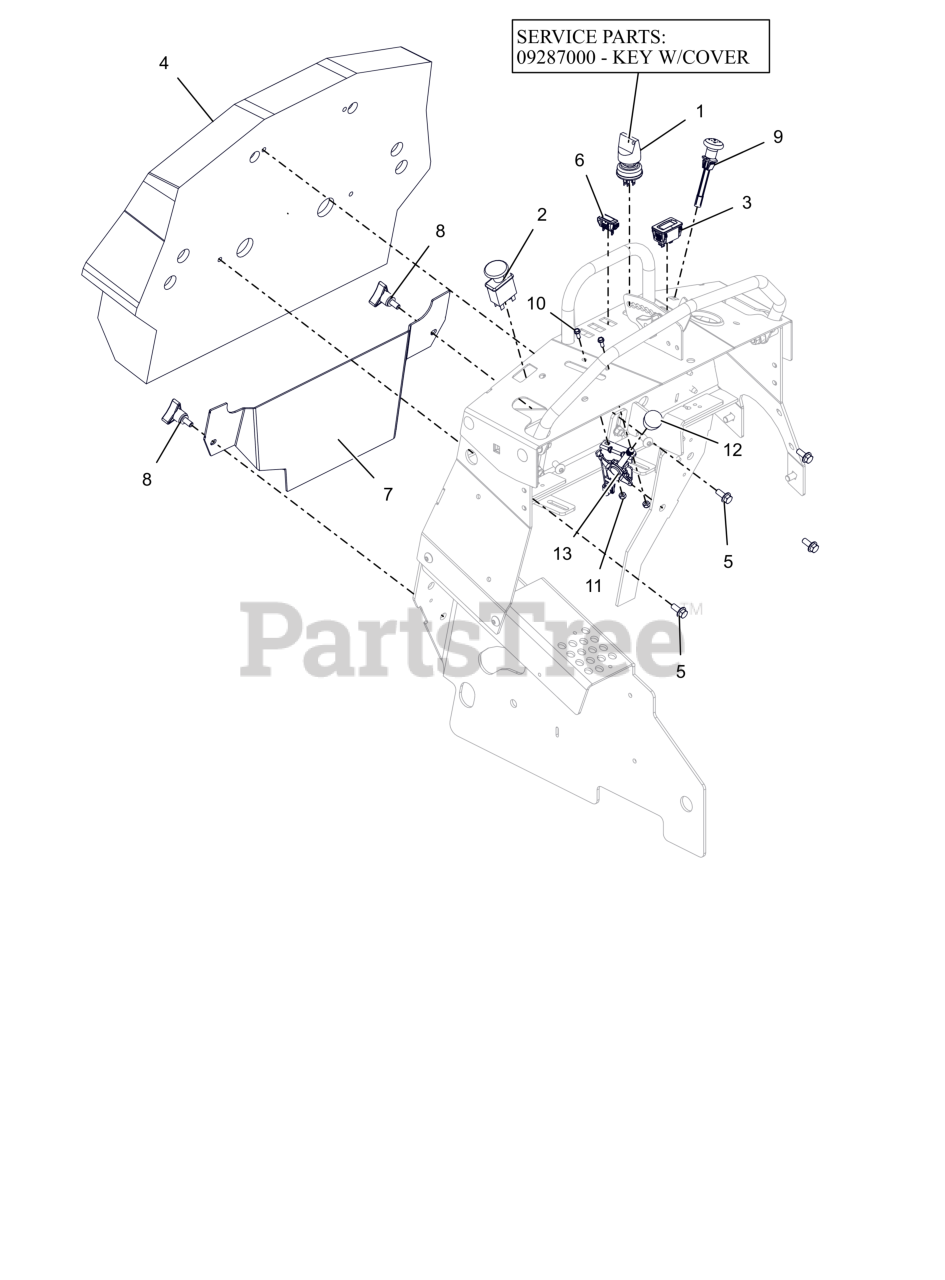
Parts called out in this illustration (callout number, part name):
1	SWITCH, IGNITION
1	KEY, W/ SHIELD
2	SWITCH, CLUTCH
3	HOUR METER
4	PAD, OPERATOR - PROSTANCE
5	BLT, SERHFWH 0.312-18X0.75 GR5 ZCC
6	LIGHT,INDICATOR
7	COVER, REAR TOWER (BLACK)
8	KNOB,WING STUD 5/16-18 X .75
9	CABLE, CHOKE (SNAP IN)
10	BLT, HWH #10-24X.50 ZCC
11	NUT-LK-NYL #10-24 G2 ZCC
12	KNOB-CONTROL-BLACK .38-16X.50
13	CABLE, PROSTANCE - CONTROL 43"
